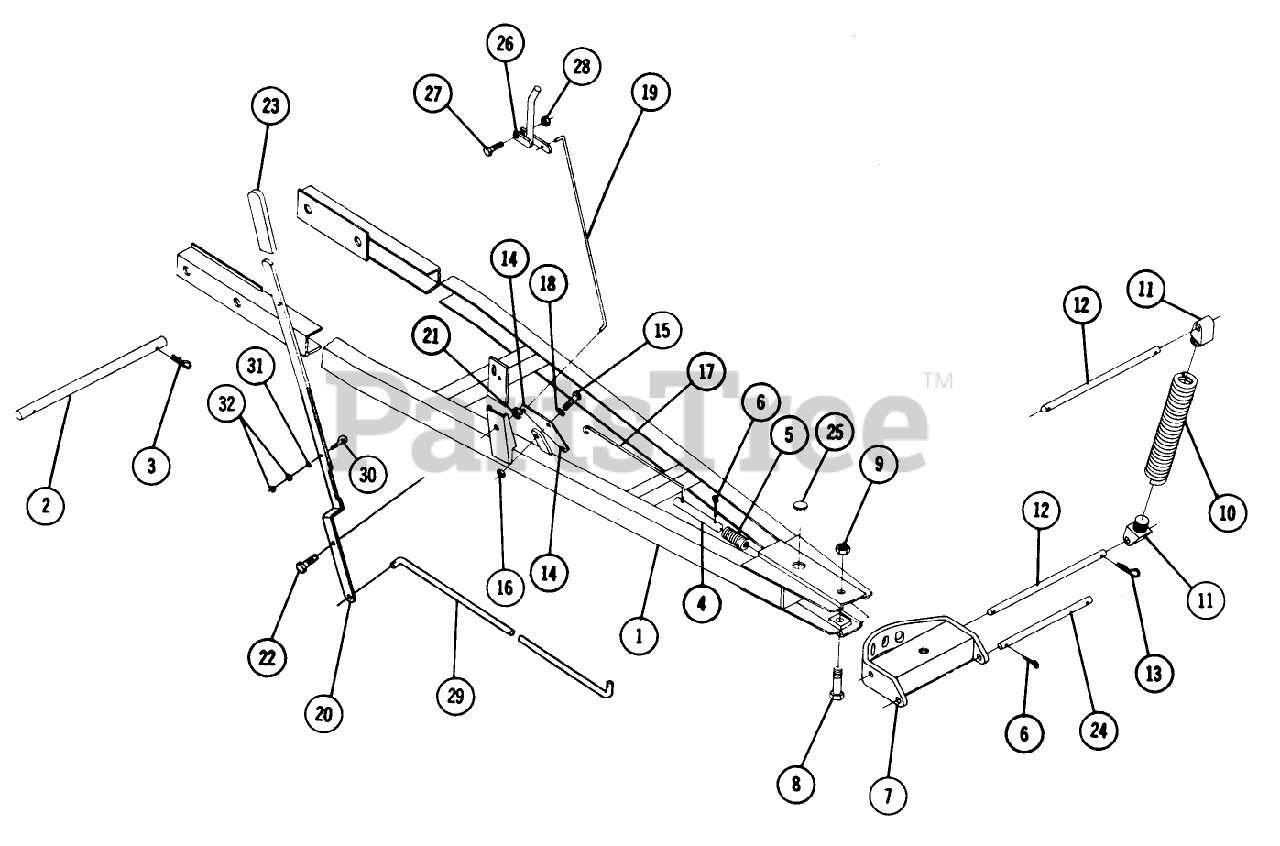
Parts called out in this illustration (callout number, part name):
1	Ass-y. Frame
2	Mounting Shaft
3	Hairpin
4	Index Pin
5	SPRING-COMPRESSION
7	Sector and Channel
8	Bolt
9	Nut
10	Spring
11	Lug
12	ROD-PIVOT, BLADE
13	Hairpin
14	Index Plate
15	BOLT
16	NUT
17	Head-Cylinder
18	Washer
19	UPPER INDEX ROD
20	Index Lever
21	Jam Nut
22	Bolt
23	GRIP
24	ROD-LOWER
25	PLUG
26	INDEX LEVER
27	Bolt
28	Nut
30	Eye Bolt
31	Lockwasher
32	Nut, #10-24 Hex
